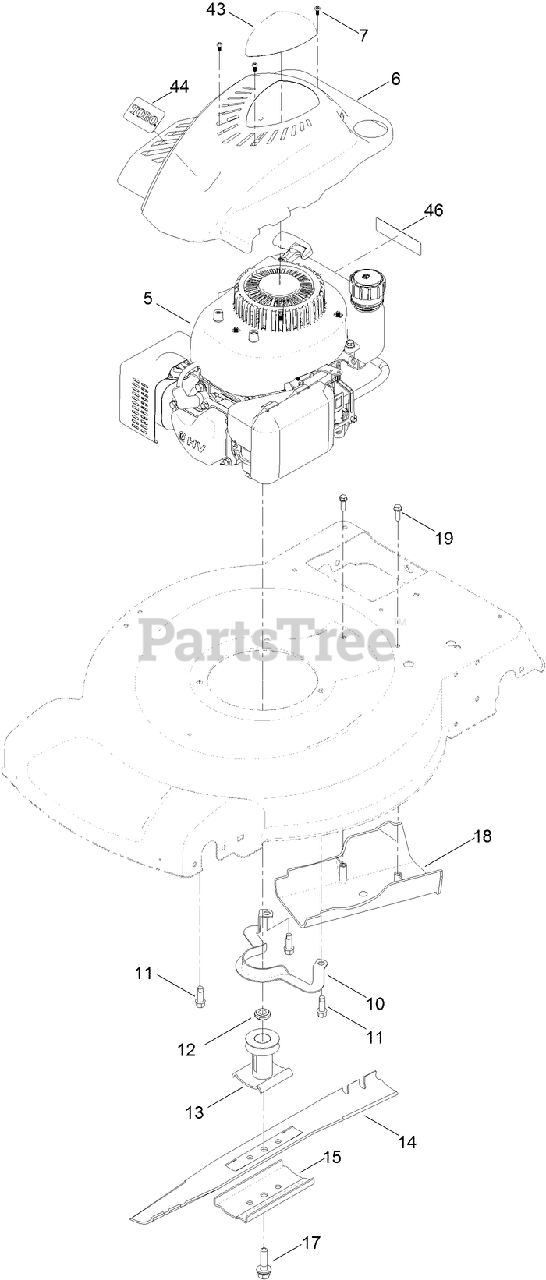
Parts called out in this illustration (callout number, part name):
5	ENGINE-1P65FC
6	SHROUD
7	SCREW-PPH
10	GUIDE-BELT
11	SCREW-TAPTITE
12	SPACER-DRIVER
13	DRIVER-BLADE
14	BLADE-22 INCH
15	SUPPORT-BLADE
17	BOLT-BLADE
18	COVER-BELT
19	SCREW-HWH
43	DECAL-SHROUD
46	DECAL-ARRESTER, SPARK
